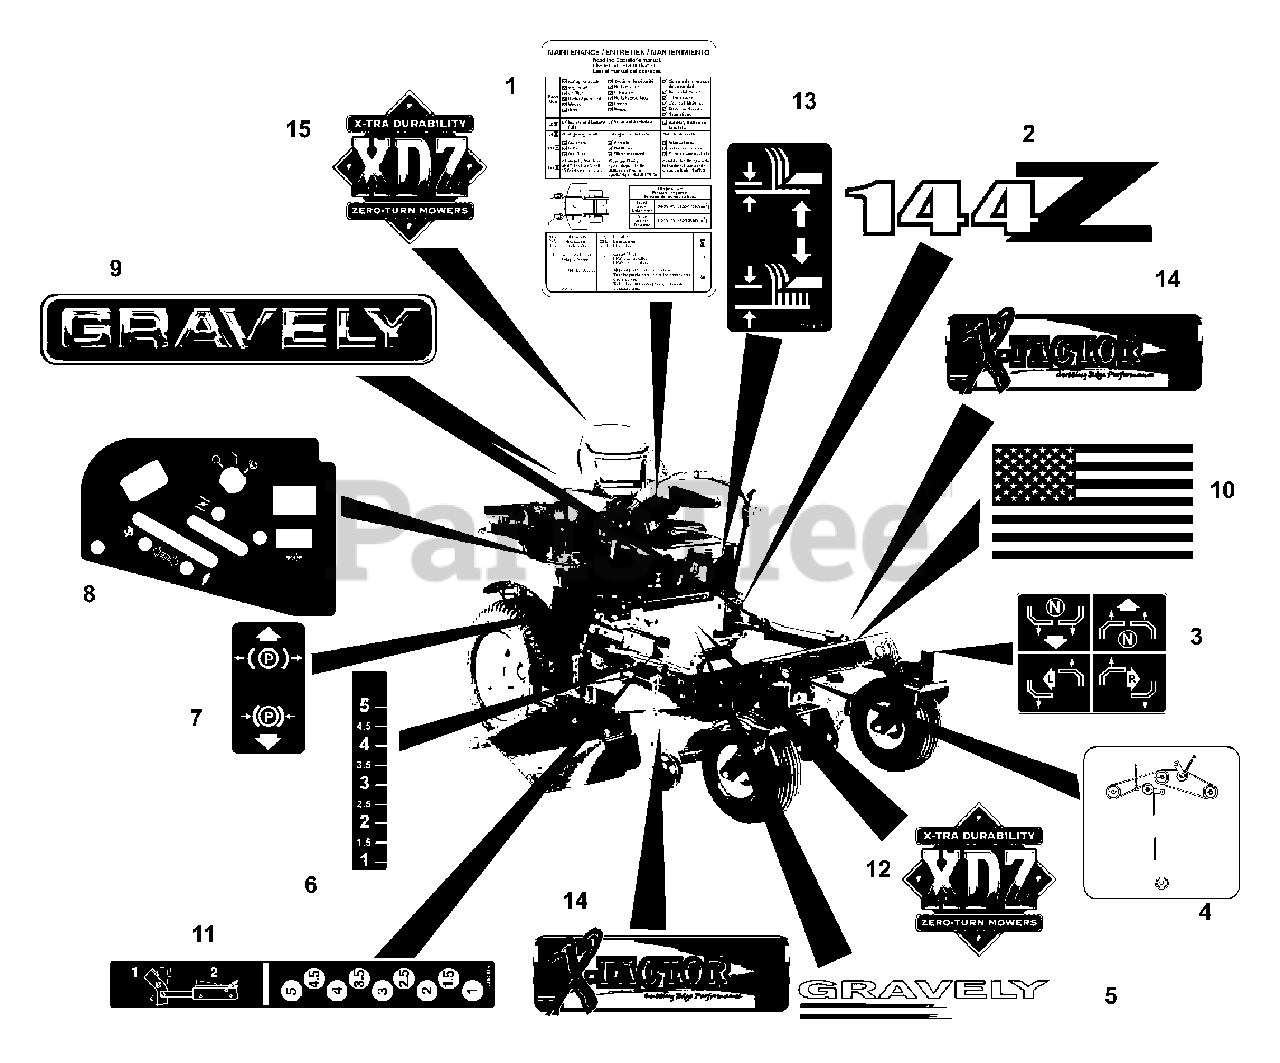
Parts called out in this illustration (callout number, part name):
1	Decal, Service Instructions
2	Decal, PM 152Z
2	Decal, PM 144Z
2	Decal, PM 148Z
2	Decal, PM 160Z
3	Decal, Instructional Steering
4	Decal, Belt Diagram
5	Decal, ZT Hood
6	Decal, Height of Cut
7	Decal, Parking Brake Lever
8	Decal, Control Panel
9	Decal, 15" Gravely Logo
10	Decal, American Flag
11	Decal, Height of Cut
12	Decal, 3" XDZ
13	Decal, Lift Lever
14	Decal, X-Factor
15	Decal, 5" XDZ
